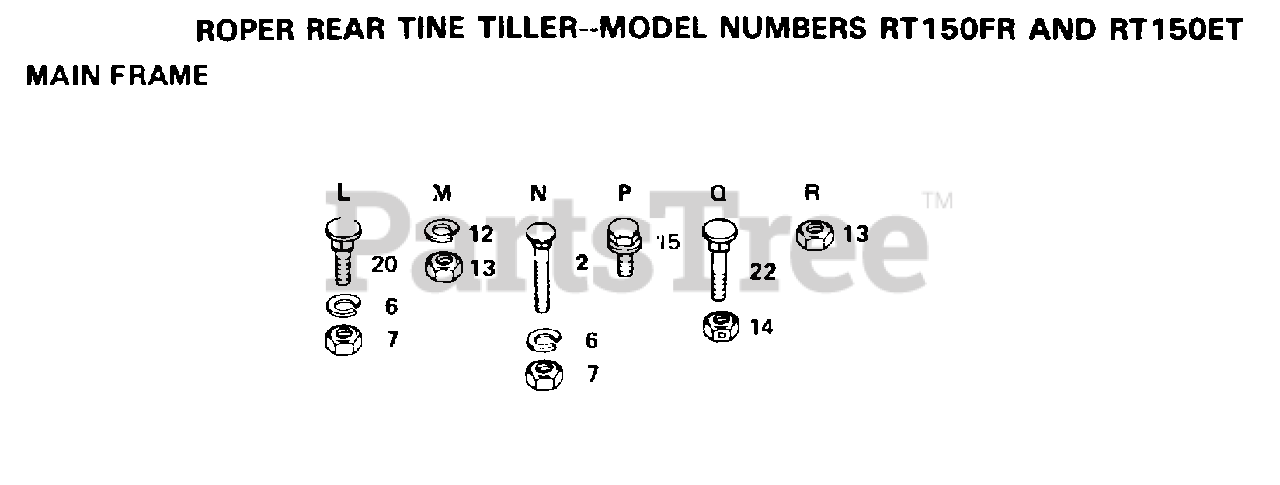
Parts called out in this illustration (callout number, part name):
2	BOLT
6	LOCKWASHER
12	LOCKWASHER
13	NUT.HEX.3/8-16UNC
20	BOLT
22	BOLT D
